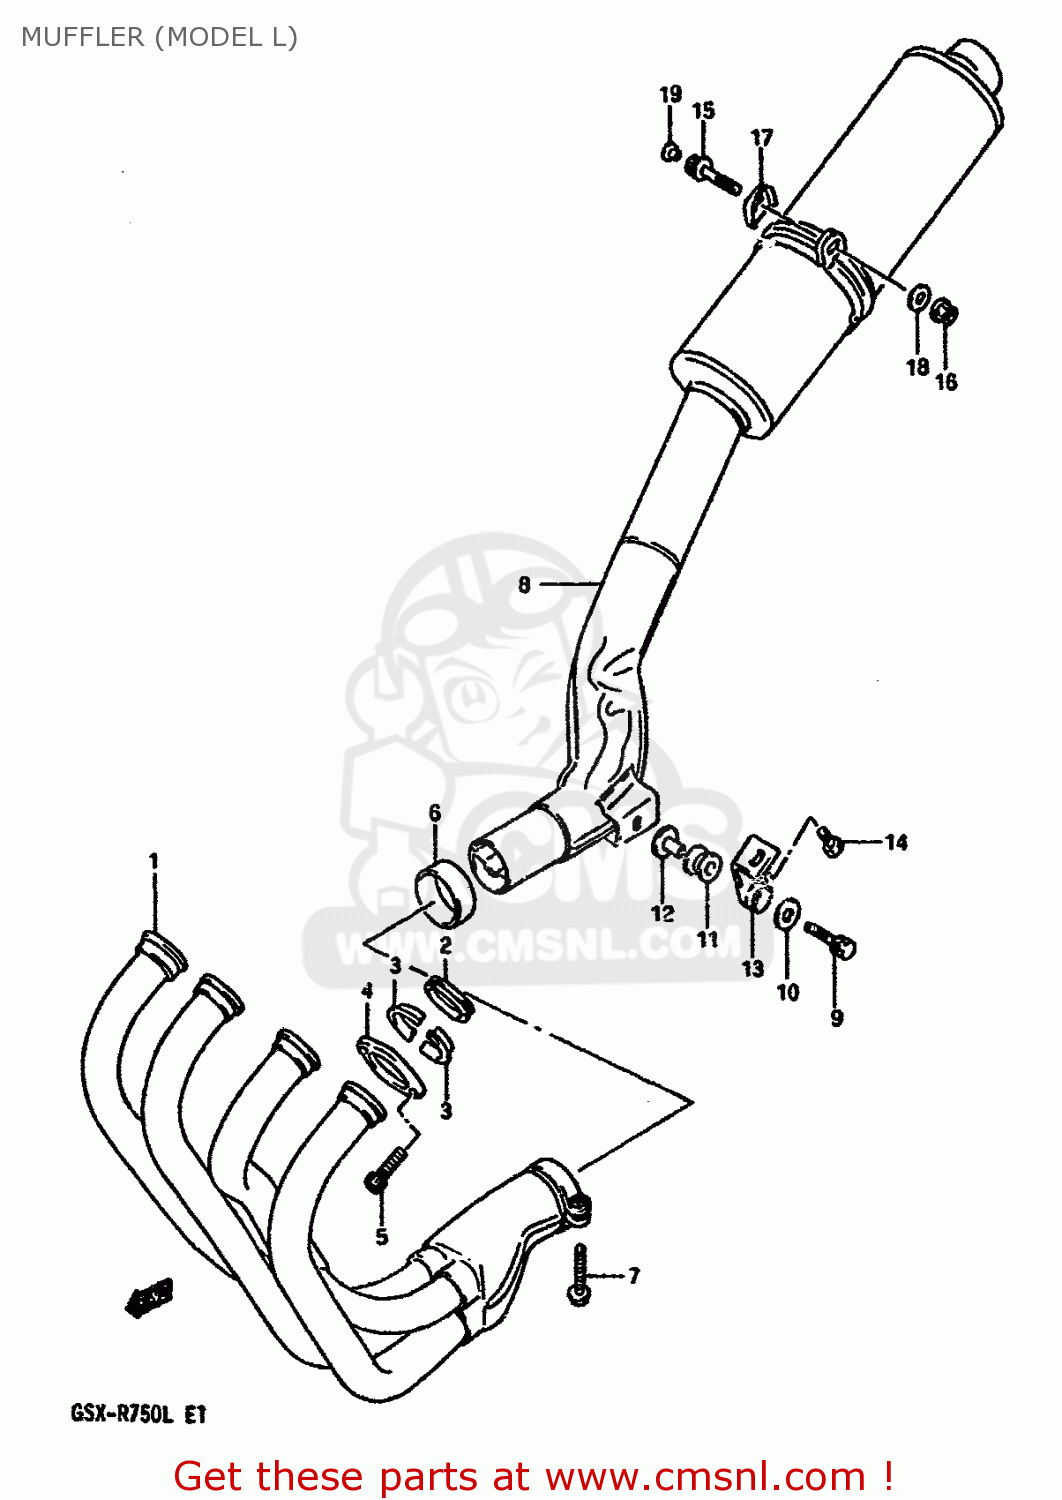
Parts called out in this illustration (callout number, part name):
1	PIPE,EXHAUST
2	GASKET,EXHAUST (NAS)
3	PLATE,EXHAUST PIPE
4	CLAMP,EXHAUST PIPE
5	BOLT
6	CONNECTOR,MUFFLER
7	BOLT 8X45
8	BODY,MUFFLER
9	BOLT 8X35
10	WASHER
11	CUSHION
12	SPACER(8.6X12X18.5)
13	DAMPER COMP,MUFFLER SUPPORT F
14	BOLT(8X20)
15	BOLT
16	NUT
17	WASHER,LOCK,8.
18	WASHER (8.5X20X1.6)
19	CAP(OD:12)
20	CUSHION
21	BOLT 10X38
22	WASHER (10.5X24X2.3)
23	NUT
24	BOLT(8X20)
